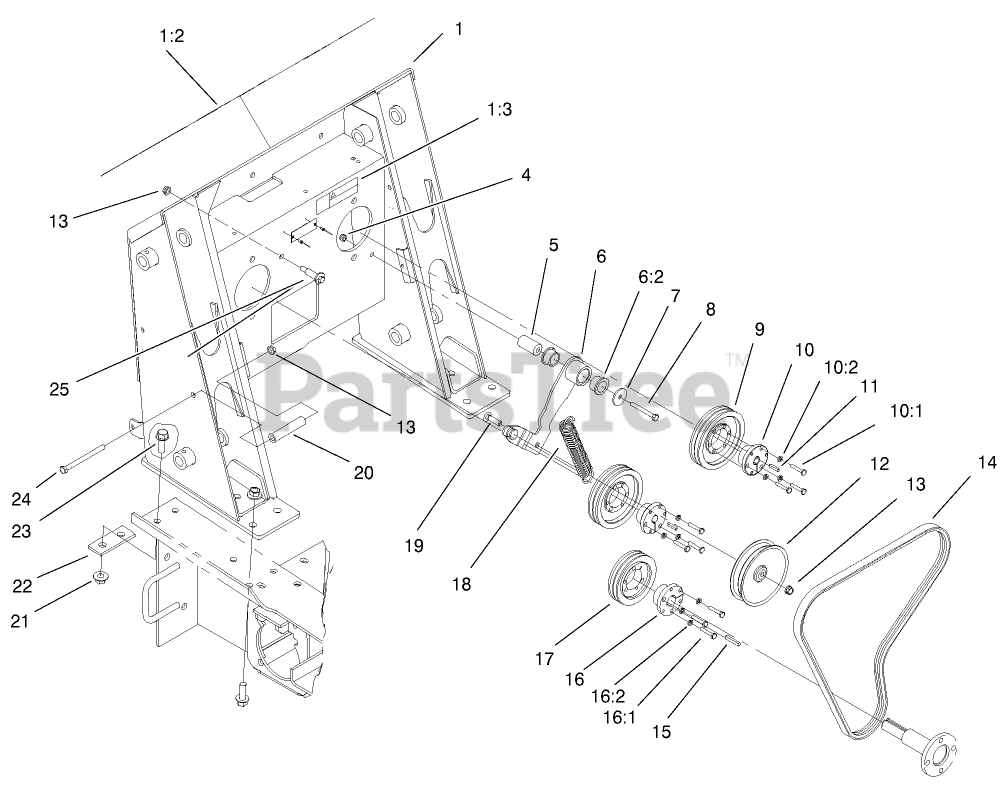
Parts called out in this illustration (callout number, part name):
1	LOADER TOWER ASM
1:2	DECAL-PANEL
1:3	DECAL-WARNING
4	NUT-LOCK, NI
5	Spacer-Mounting
6	IDLER ARM ASM
6:2	BUSHING-FLANGE
7	WASHER-FLAT
8	SCREW-HH
9	SHEAVE
10	BUSHING
10:1	SCREW-HH
10:2	WASHER-LOCK / SP
11	KEY-PUMP
12	PULLEY-IDLER
13	NUT-LOCK, NI
14	V-BELT
15	KEY-SQUARE
16	BUSHING
16:1	SCREW-HH
16:2	WASHER-LOCK / SP
17	PULLEY
18	Spring-Extention
19	SCREW-CARR
20	TUBE-SPACER
21	NUT-LOCK, FLANGE
22	PLATE-STIFFENER
23	SCREW-HHF
24	SCREW-HH
25	BOLT-WHEEL
